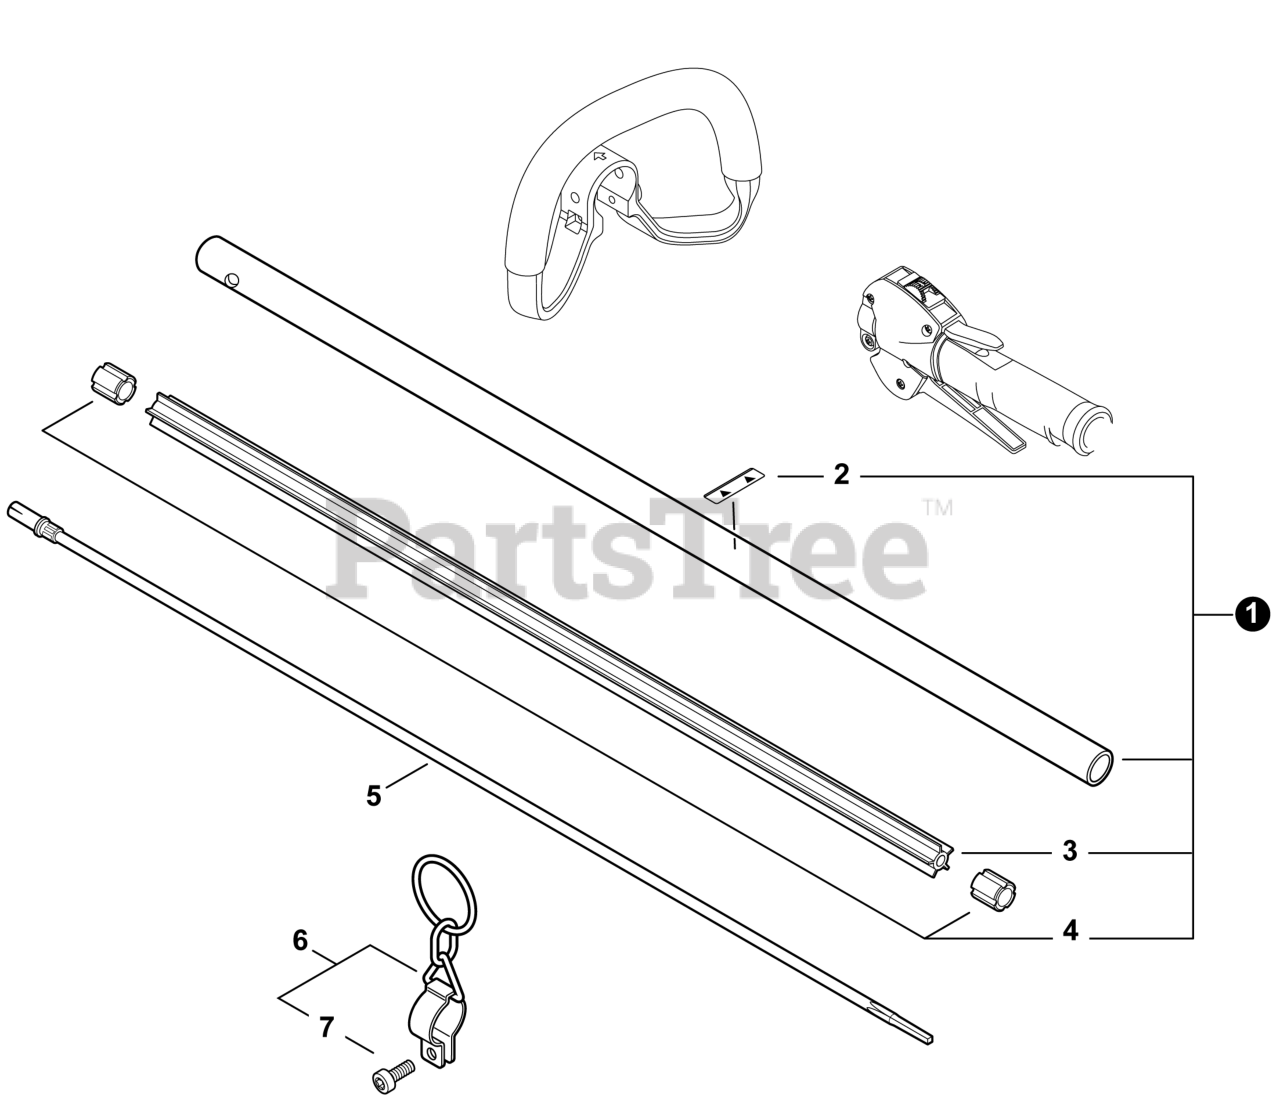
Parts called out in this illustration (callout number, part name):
1	MAIN PIPE ASSY
2	LABEL - ALIGNMENT
3	LINER - FLEXIBLE
5	DRIVESHAFT - FLEXIBLE
6	HANGER SET, HARNESS
7	BOLT, TORX 5x12
